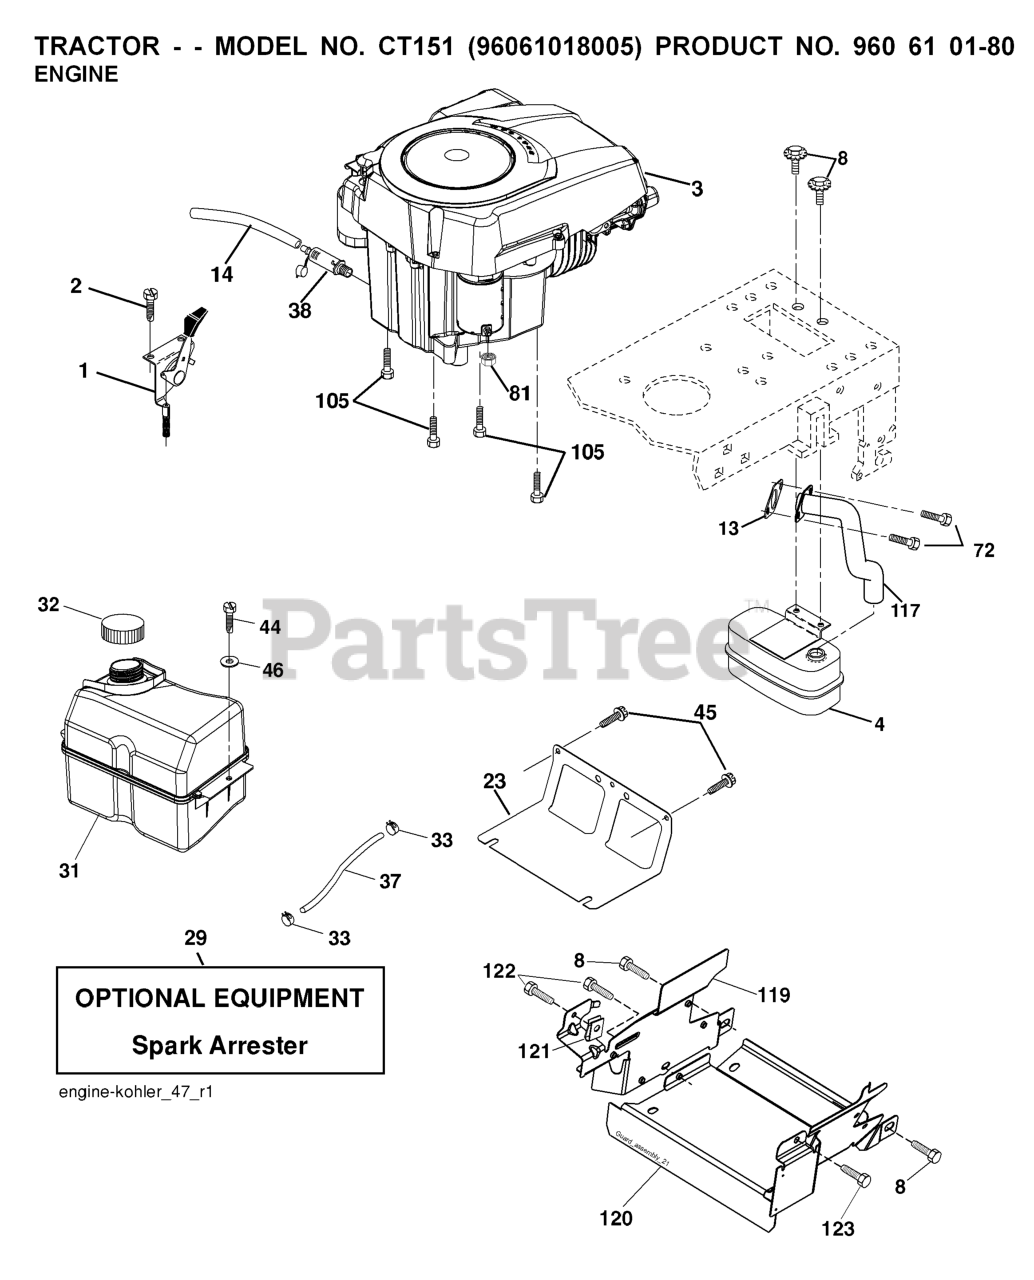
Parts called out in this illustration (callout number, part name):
1	CONTROL.TH/CK.C.
2	SCREW
4	MUFFLER.SINGLE.CYL.KOHL/B&S
8	BOLT.5/16-18UNCX3/4 W/SEMS.BLK
13	GASKET.EXHAUST.KOHLER
14	TUBE, DRAIN OIL ASM.
23	SHIELD.BROWNING.DBR.GUARD
29	KIT.SPARK ARRESTOR 794945 B&S
31	RP TANK FUEL FRT 1.5 GAL
32	FUEL CAP
33	HOSE CLAMP
37	LINE.FUEL.20
38	PLUG DRAIN OIL EASY
44	SCREW HEXWSHR 1/4-20X3/4
45	SCREW, 3/8-16X3/4
72	SCREW.SOCKET HD.5/16-1
81	NUT
105	SCREW 3/8-16X1
117	RP.TUBE.EXHAUST.KOHL.COURAGE
119	LENKRAD
120	GUARD 532199767
122	SCREW.1/4-20X5/8
123	SCREW, 5/16-18 X 1/2
